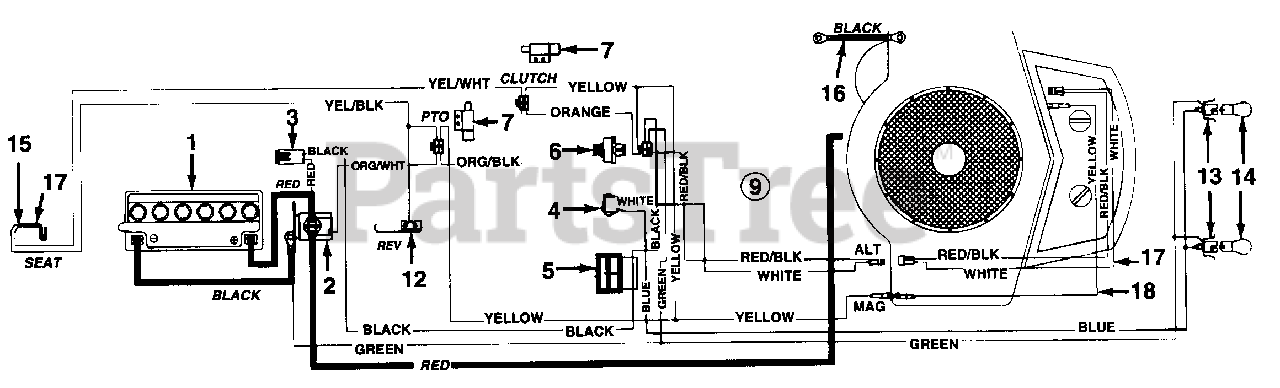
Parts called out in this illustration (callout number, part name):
1	Battery
2	Solenoid
3	Fuse 7.5 Amps
4	Light Switch
5	Ammeter
6	Ignition Switch
7	Safety Switch
9	Wire Harness
12	Safety Switch (Reverse)
13	Socket
14	Bulb (Headlight)
15	Safety Switch (Seat)
16	Ground Wire 7.5" Lg.
17	Safety Switch (Seat)
18	Harness Adapter
